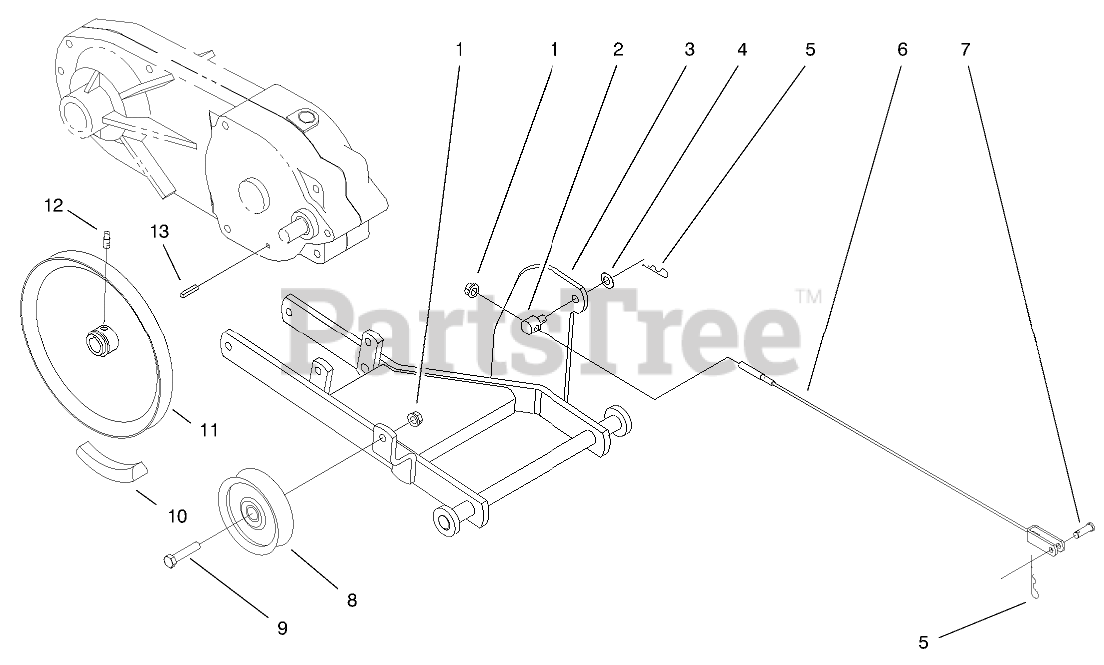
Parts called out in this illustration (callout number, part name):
1	NUT-LOCK, NI
2	TRUNNION
3	WA - HITCH B
4	WASHER-FLAT
5	PIN-HAIR
6	LIFT CABLE ASM
7	PIN-CLEVIS
8	PULLEY-IDLER
9	SCREW-HH
10	V-BELT, REAR
11	PULLEY
12	SCREW-SQH
13	KEY-STRAIGHT
